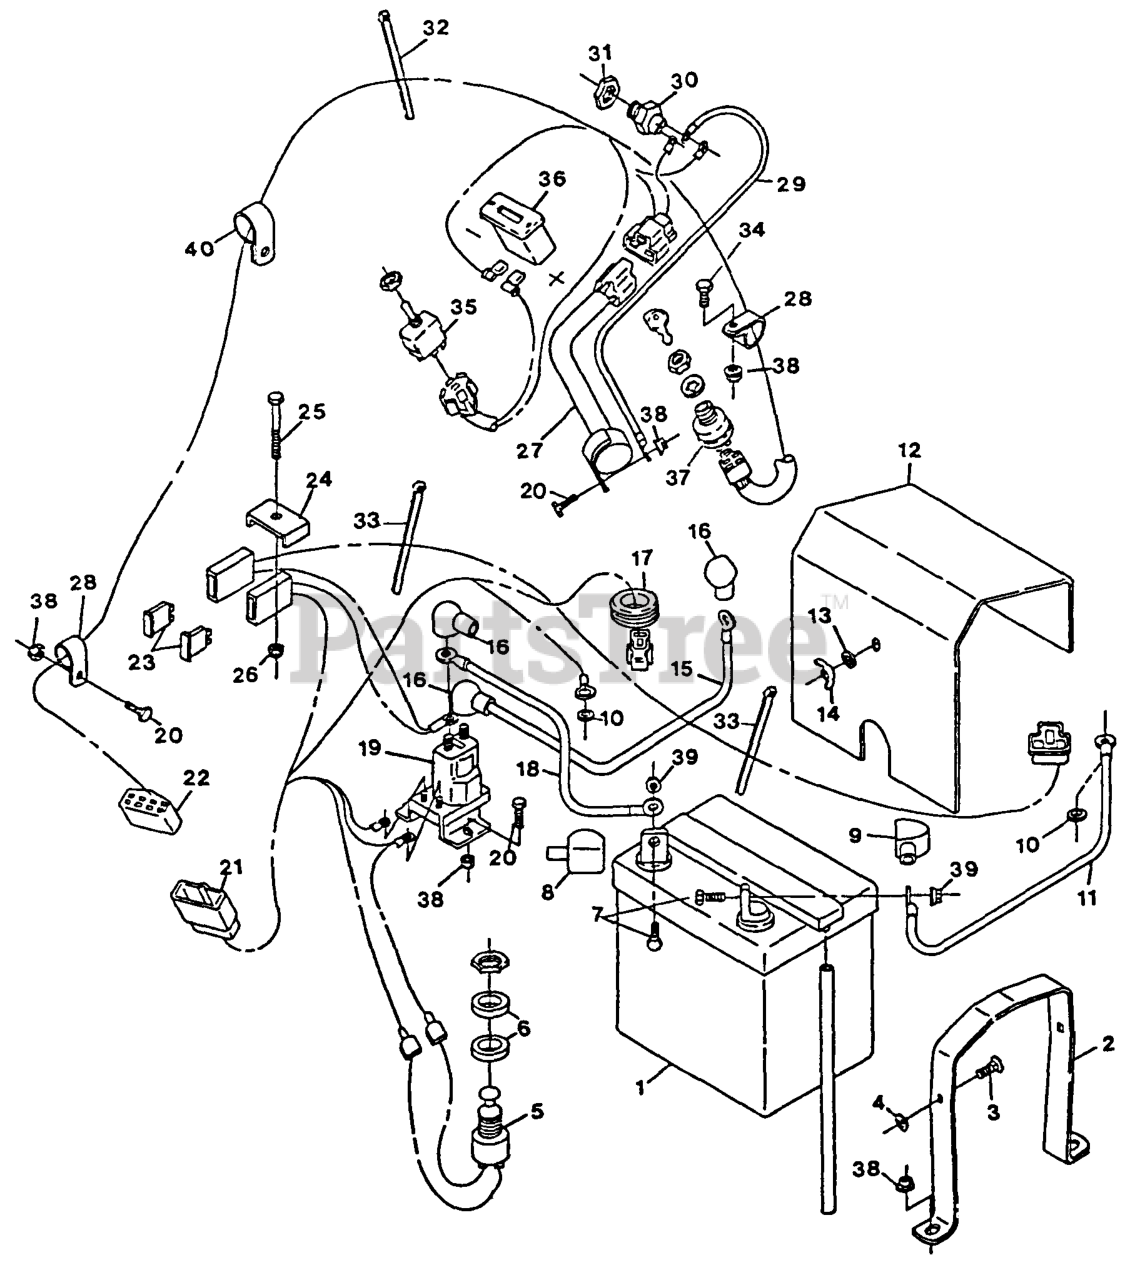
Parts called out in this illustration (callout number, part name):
1	Battery, 12v Manifold
2	STRAP,BATTERY HOLDDOWN
3	BOLT-CARR
4	NUT-RETAINING
5	SWITCH,PUSH BUTTON
9	INSULATOR, BATTERY -
14	NUT-WING
16	INSULATOR-SOLENOID
17	GROMMET
21	HARNESS,HYDRO ENGDECK
23	FUSE-BLADE TYPE, 20 AMP
24	CLIP-FUSE BLOCK PLTD
28	CLIP-LOOM
30	SWITCH,OPERATOR CNTRL
32	TIE-PLASTIC
33	TIE-CABLE
35	SWITCH,W/TERM CLIPPD
36	METER-HOUR
40	CLIP-LOOM
